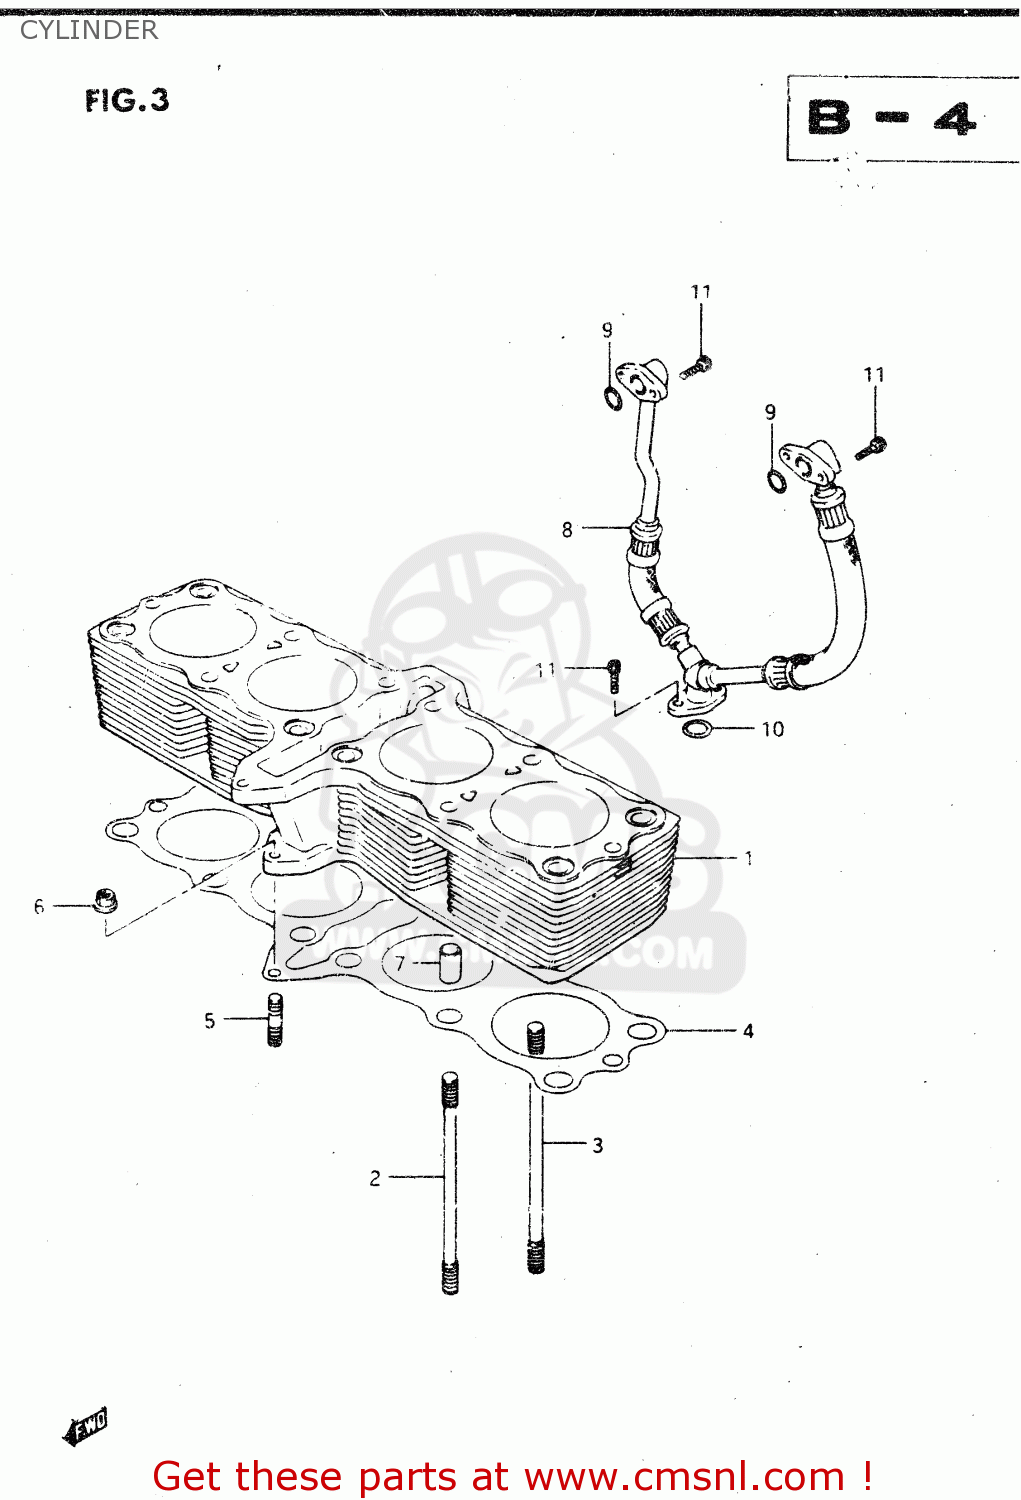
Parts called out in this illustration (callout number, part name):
1	CYLINDER
2	STUD
3	BOLT,STUD
4	GASKET,CYLINDER (NAS)
5	STUD BOLT L:20
6	NUT 6MM
7	PIN
8	HOSE
9	O RING(D:2.4,ID:12.3)
10	O RING(D:2.4,ID:15.8)
11	BOLT
